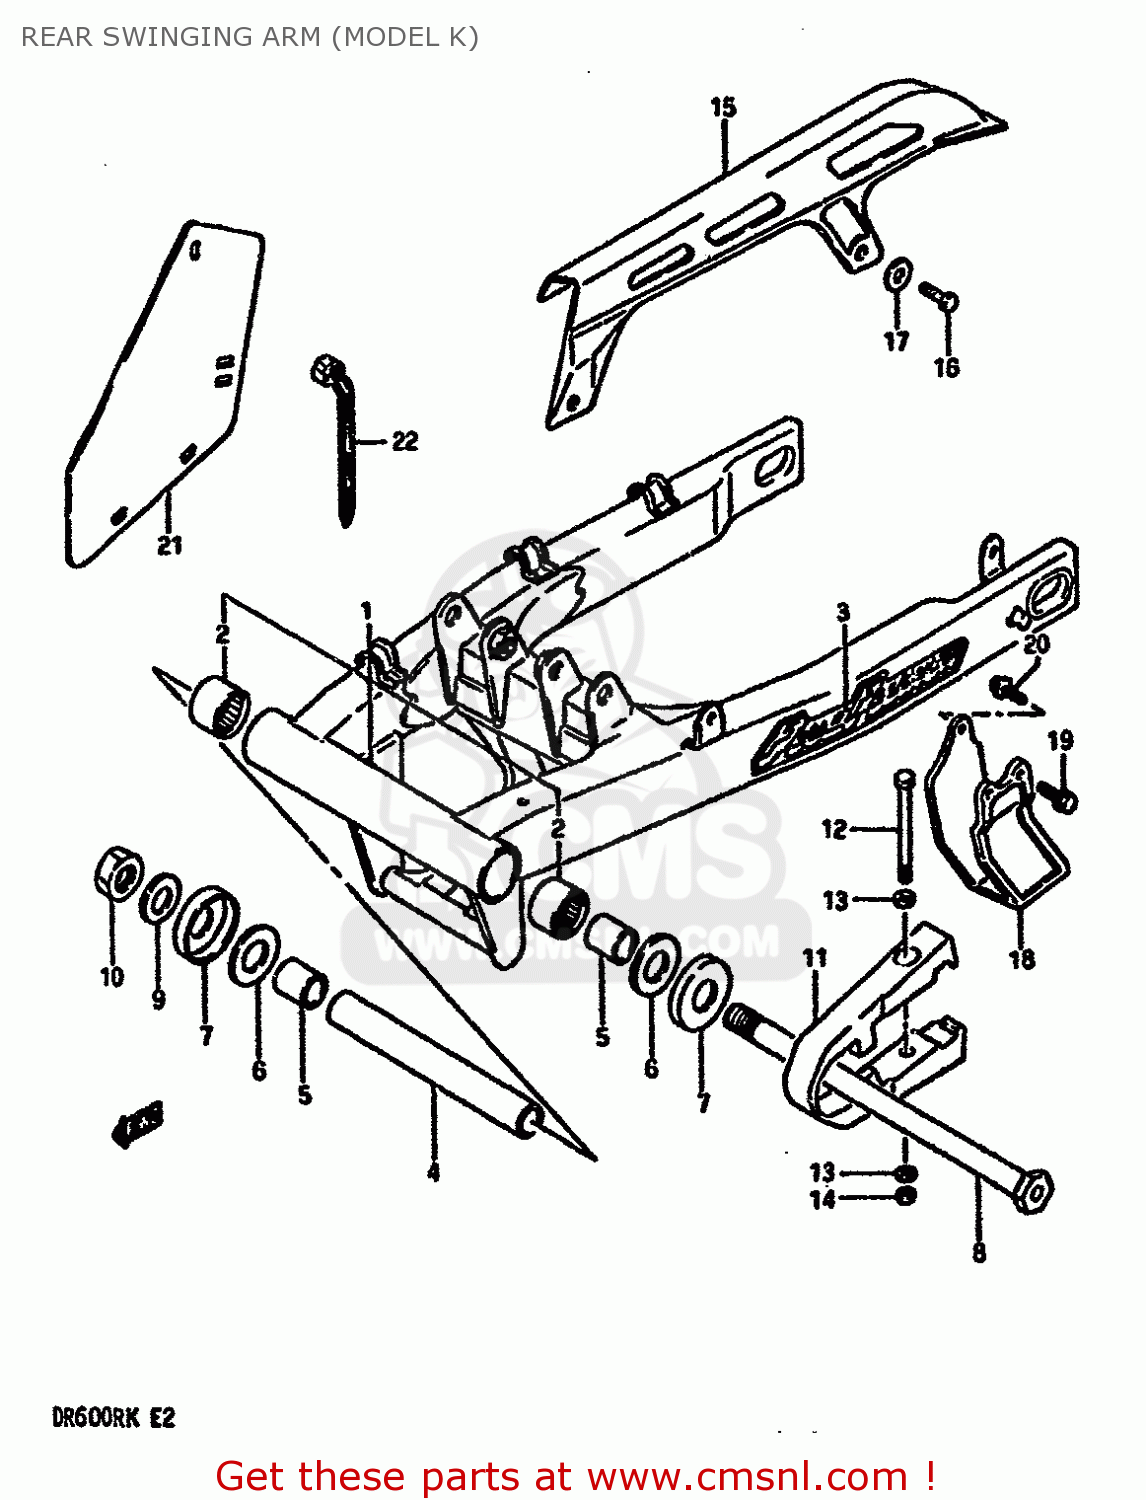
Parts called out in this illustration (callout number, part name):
1	SWINGING ARM ASSY,REAR (SILVER)
2	BEARING(22X29X20)
3	EMBLEM (YELLOW/BLUE)
4	SPACER,RR SWGARM PIVOT CTR
5	SPACER,RR SWGARM PIVOT
6	WASHER
7	SEAL,RR SWGARM PIVOT DUST
8	SHAFT,RR SWINGINGARM PIVOT
9	WASHER
10	NUT 16MM
11	BUFFER,CHAIN TOUCH DEFENSE
12	BOLT,TOUCH DEFENSE FTG
13	WASHER(5.2X16X1)
14	NUT
15	CASE,CHAIN
16	BOLT
17	WASHER
18	GUIDE,CHAIN
19	BOLT
20	BOLT 6X16
21	GUARD, CHAIN
22	CLAMP(L:125)
23	24-1
24	BOLT 8X32
25	WASHER
26	WASHER
27	NUT
28	PIN 20X20
29	GUARD, CHAIN
30	CLAMP(L:125)
